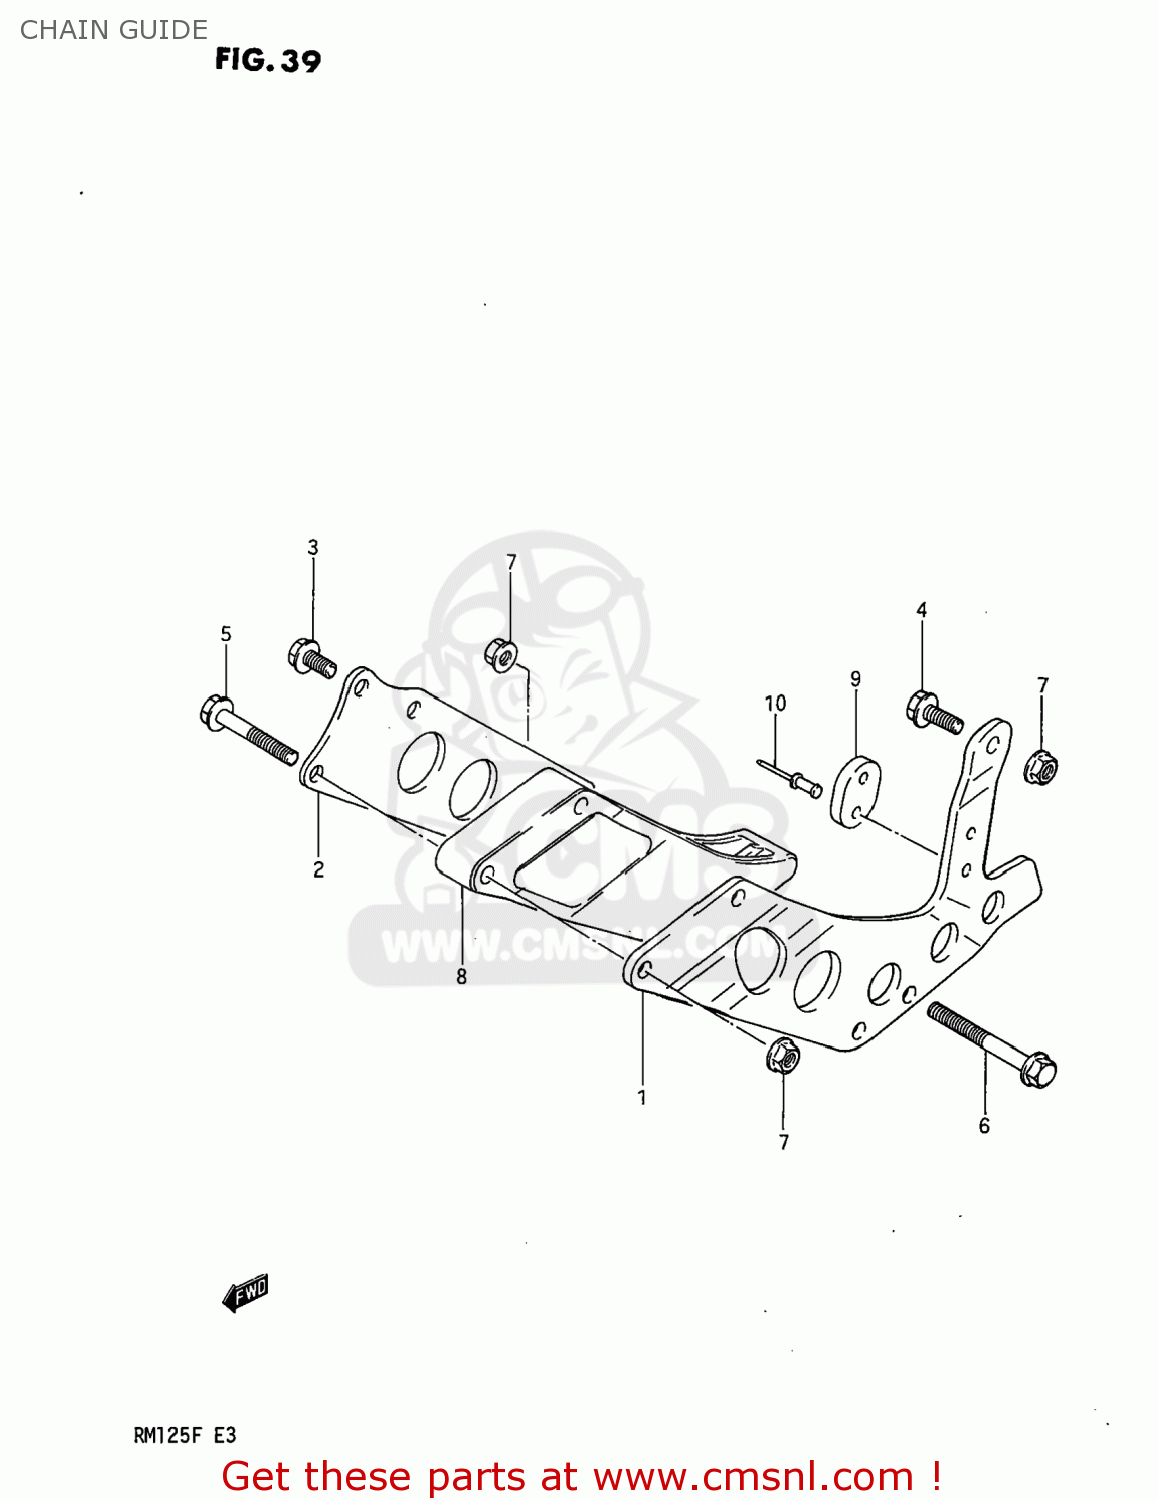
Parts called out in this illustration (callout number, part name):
1	PLATE,CHAIN GUIDE,OUTER
2	PLATE,CHAIN GUIDE,INNER
3	BOLT
4	BOLT
5	BOLT
6	BOLT,UNDER
7	NUT
8	DEFENSE,CHAIN GUIDE
9	PAD,CHAIN GUIDE
10	RIVET
